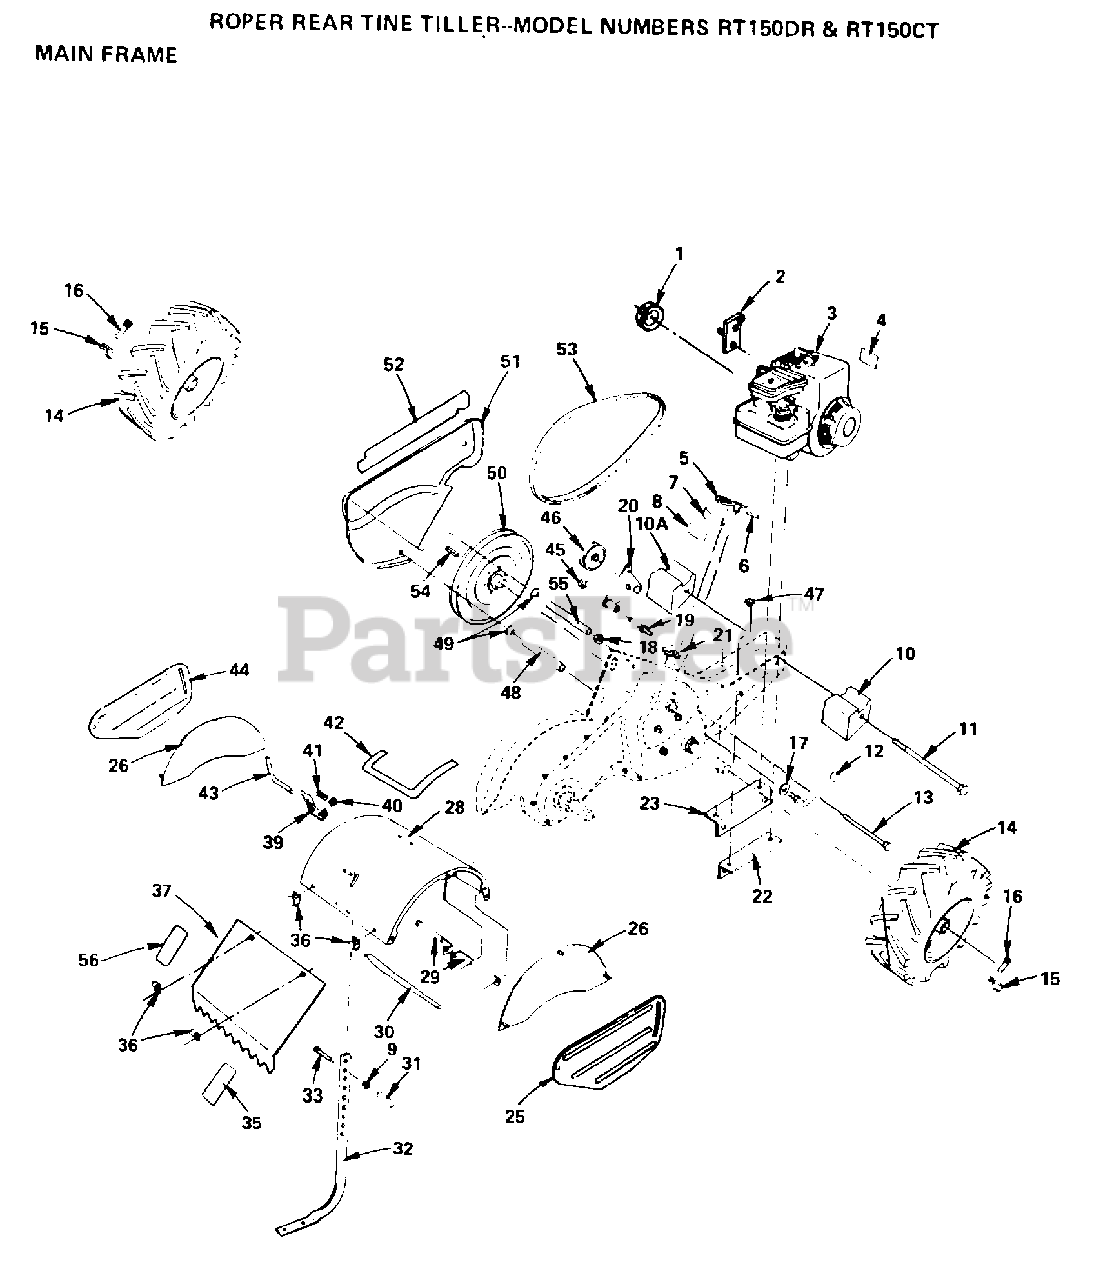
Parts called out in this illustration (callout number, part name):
2	BRACKET ASSY CRT
7	PANEL TI
8	DECAL CRT
9	NUT.HEX.3/8-16UNC
10	COUNTERWEIGHT CRT
10A	COUNTERWEIGHT CRT
11	BOLT CRT
13	BOLT-HEX TI
15	RETAINER M
17	WASHER
18	NUT.HEX.5/16-18
19	SHIFT ARM CRT
21	CONDIUT CLIP T
22	BRACKET RH CRT
23	BRACKET LH CRT
31	GRIP CRT
33	BOLT
36	HINGE CRT
37	SHLD-LEVELING TI
39	LATCH BRACKET TI
40	KLIP RING TI
41	SPRING TI
42	DECAL - TINE SHIELD
43	STAKE PIN TI
45	KLIP RING
46	PULLEY-IDLER TI
49	WASHER
50	"SHEAVE 10"" CRT"
54	KEY T
56	DECAL - DEPTH ADJUSTMENT
